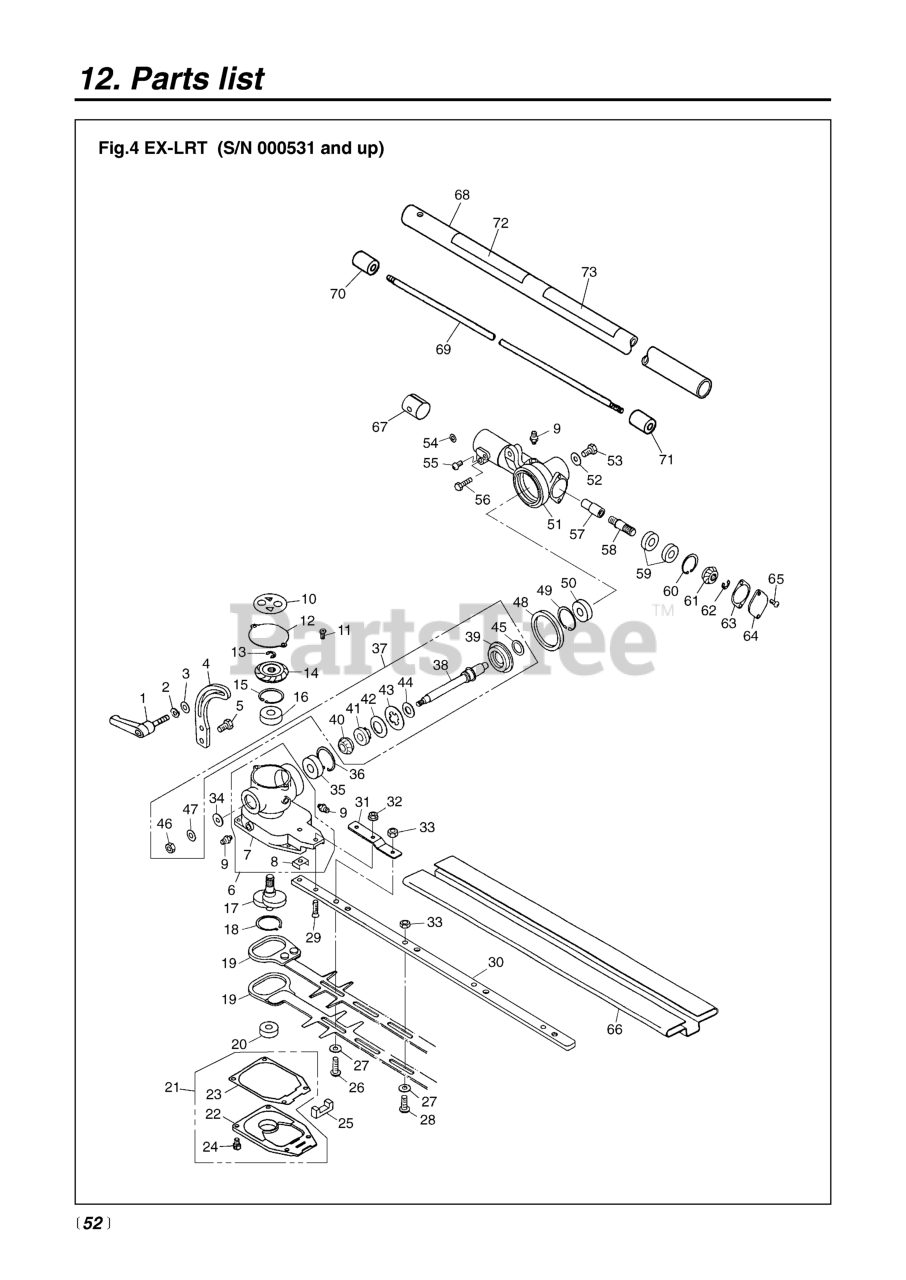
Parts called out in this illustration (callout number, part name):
2	WASHER, M6 X 15
3	WASHER, 6X15X2.0
4	PLATE (RPLS-13140)
6	CASING (RPLS -13210)
7	CASING A
8	PLATE
9	FITTING, GREASE
11	SCREW, M4 X 8
13	RING, SNAP
14	GEAR, BEVEL
15	RING, SNAP, M26 X 1.2
16	BEARING
17	CRANKSHAFT
18	RING, SNAP, M28 X 1.5
19	BLADE (RPLS -13410) 18
20	BEARING
21	COVER SET (RPLS -13440)
22	COVER
23	GASKET
24	BOLT (RPLS 6782-13450)
25	FELT
27	WASHER (RPLS 3873-11760)
28	SCREW
29	SCREW, M5 X 20
30	PLATE, GUIDE
31	PLATE (RPLS 6780- )
32	NUT, M5
33	NUT, M6
34	WASHER, 6X15X2.0
35	BEARING
36	RING, SNAP, M22 x 1.2
37	KIT, SHAFT (RPLS 6782-13610)
38	SHAFT
39	GEAR
40	GEAR (C)
41	PUMP, DIAPHRAM
42	WASHER, SPRING
43	PLATE
44	WASHER
45	WASHER
46	NUT, M6 X 5
47	WASHER, M6 X 15
48	O-RING
49	RING, SNAP, M26 X 1.2
50	BEARING
51	CASING
52	WASHER, 6X15X2.0
54	WASHER
55	BOLT, M5 X 10
56	BOLT
57	JOINT (REPLACES T3078-13810)
58	SHAFT, GEAR
59	BEARING
60	RING, SNAP, M22 x 1.2
61	GEAR, BEVEL
62	RING, SNAP
63	PACKING
64	COVER, STOPPER KIT
65	SCREW, M4 X 8
66	COVER, BLADE
68	PIPE COMPLETE
69	SHAFT
70	JOINT, SHAFT (RPLS -12240)
71	SPACER
72	NAMEPLATE
73	PLATE, CAUTION
